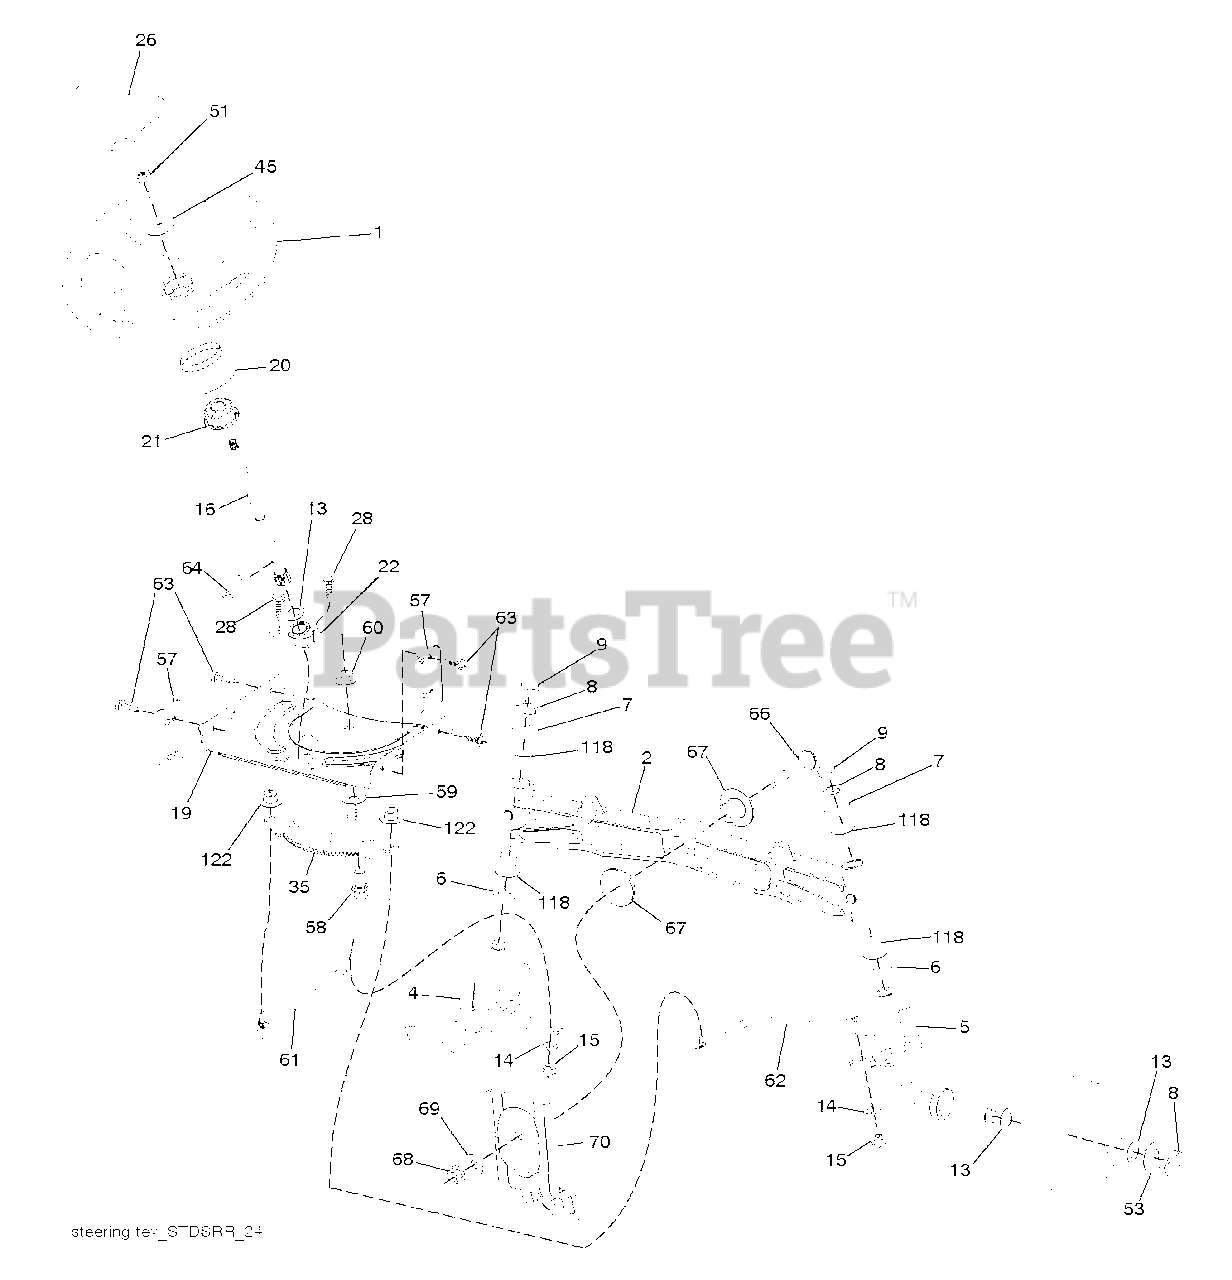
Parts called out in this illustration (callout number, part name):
1	WHEEL.STEERING.STDSRR.BLK/OV
2	AXLE.SVC.ASM CAST IRON.TEX
4	SPINDLE.WELDED.LH.15"TEX
5	SPINDLE.WELDED.RH.15"T
8	RING CLIP
9	CAP.SPINDLE
14	WASHER, LOCK 3/8
15	NUT CROWNLOCK 3/8-24
16	SHAFT.STEER.STEALTH.DD
19	PLATE.STEER.DDL.NLT/NG
21	STEERING.WHEEL.ADAPTER
22	STEERING.SUPT.LOWER.
26	CAP.WHL.STRNG.STDSRRD.SRS.BLK
28	SCREW, 3/8-16X3/4
45	WASHER 9/16"ID, 2 3/8"OD
51	NUT.HEX.1/2-20
53	WASHER.HARDENED
57	BRACKET.UPSTOP.TEX
58	BOLT.SHOULDER.SECTOR.P
59	WASHER.THURST.SECTOR.S
60	NUT FLANGE LOCK 5/8-11
61	DRAGLINK.LH.BALLSTUD.D
62	DRAGLINK.RH.BALLSTUD.D
63	SCREW
64	RETAINER.CLIP.SPRING.S
66	BOLT HEX FGHD 7/16-14 X 3 SERR
67	BUSHING.PM.FRONT AXLE
68	NUT.LOCK.FLANGE.7/16
69	WASHER.1.5X.505X.118
70	BRKT.DECK.SUSPENSION.F
118	BUSHING, AXLE CAST
